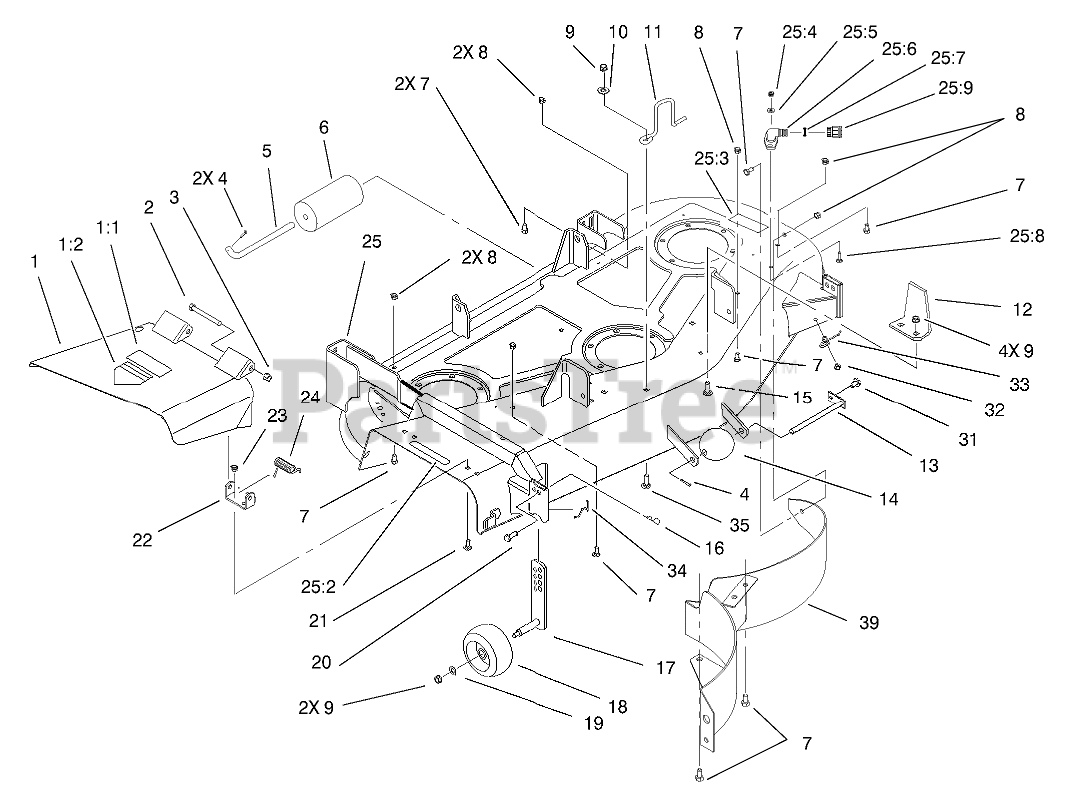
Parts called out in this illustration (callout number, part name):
1	Deflector ASM (only on: 78370)
1	Deflector ASM (only on: 78452)
1:1	Decal-Danger (only on: 78370)
1:1	Decal-Danger (only on: 78452)
1:2	Decal-Danger (only on: 78452)
1:2	Decal-Danger (only on: 78370)
2	SCREW-HH
3	NUT-HEX
4	PIN-COTTER
5	SHAFT-ROLLER, REAR
6	ROLLER-DECK
7	Screw-HH (only on: 78370)
8	Nut-Lock,NI (only on: 78370)
9	NUT-LOCK, NI
10	WASHER
11	GUIDE-BELT
12	Bracket Guide
13	SHAFT ASM
14	ROLLER
15	BOLT-CARR
16	PIN-HAIR
17	GAGE-WHEEL
18	WHEEL-GAGE
19	WASHER-FLAT
20	PIN-CLEVIS
21	SCREW-CARR
22	BRACKET-PIVOT
23	NUT-LOCK, NI
24	SPRING
25	Deck ASM (only on: 78370)
25	Deck ASM (only on: 78452)
25:2	Decal-Caution (only on: 78370)
25:2	Decal-Danger (only on: 78452)
25:3	Decal-Danger (only on: 78452)
25:3	Decal-, Danger (only on: 78370)
25:4	Nut-Lock, NI (only on: 78370)
25:5	Washer-Flat (only on: 78370)
25:6	Fitting-Washout (only on: 78370)
25:7	O-Ring (only on: 78370)
25:8	Screw-CARR (only on: 78370)
25:9	Connector-Hose (only on: 78370)
31	SCREW-HWHTF
32	SCREW-HHFTF
33	SPRING-GAGE WHEEL, LH
34	SPRING-GAGE WHEEL, RH
35	SCREW-CARR
39	Baffle (only on: 78370)
